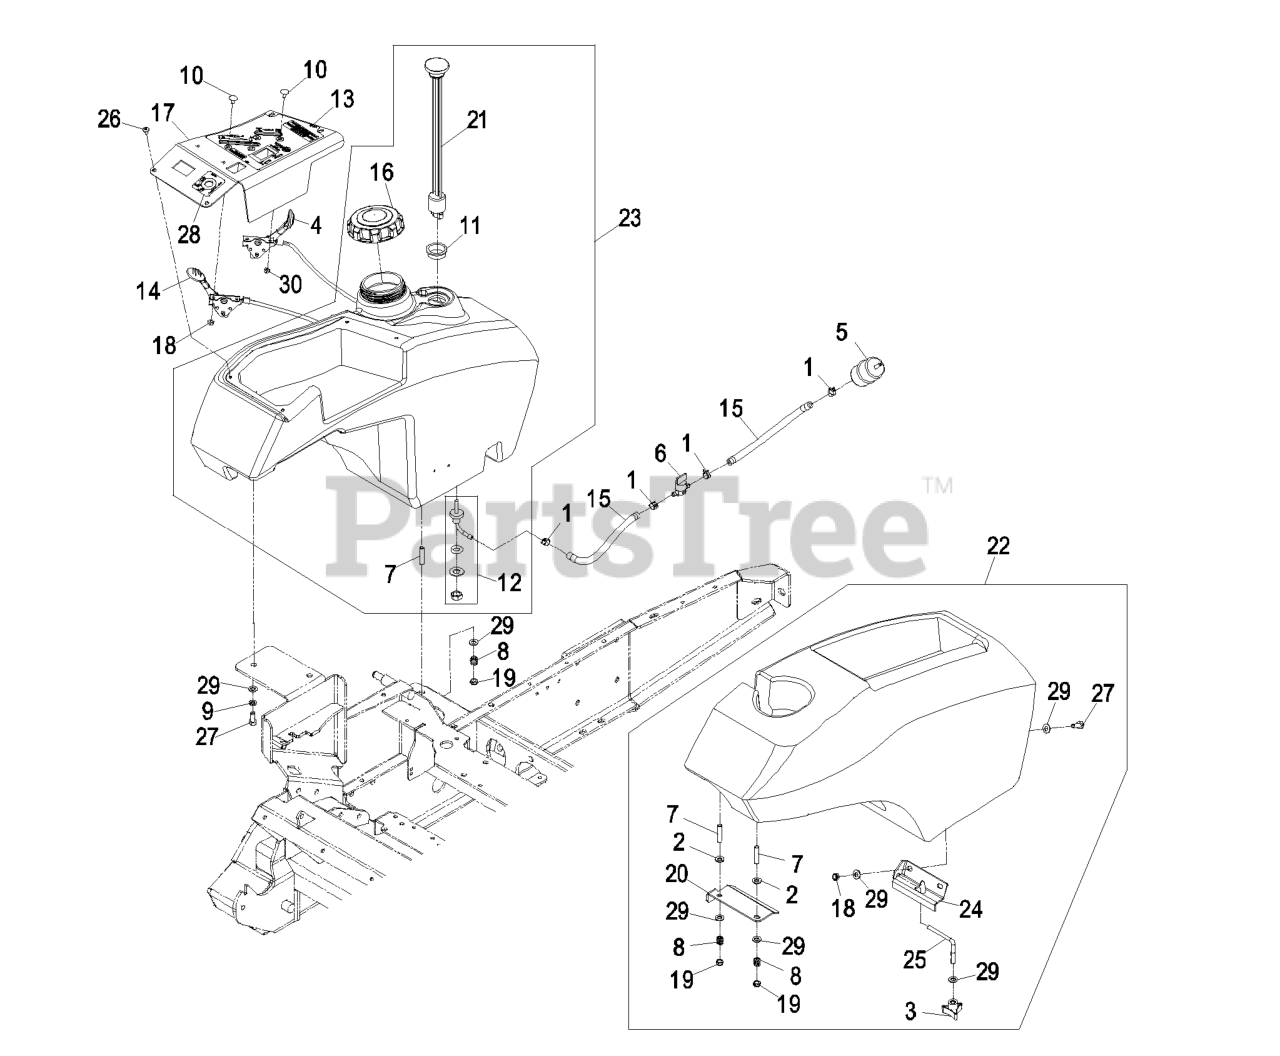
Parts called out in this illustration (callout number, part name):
2	WASHER-SPRING
3	KNOB-3 PRONG
4	CONTROL,CHOKE
5	Kohler Part No. 2405010 Fuel Filter
6	VALVE-FUEL
7	STUD
8	SPRING-TANK, FUEL
9	WASHER-LOCK
10	BOLT-CARR
11	CONTACT ORDER SERVICES
12	FITTING-FUEL, BULKHEAD
13	DECAL,CONTROL FMZ A/C
14	CONTROL,THROTTLE
15	HOSE-FUEL
16	CAP-FUEL, GAS
17	ASM,CONTROL PANEL FMZ A/C
18	NUT-LOCK, NI
19	NUT-LOCK, NI
20	HOOK,FENDER (PLATED)
21	Gauge, Fuel
22	ASM,FENDER FMZ
24	BRACKET,FENDER
25	BOLT,FENDER
26	SCREW-PPH
27	SCREW-HH
28	DECAL,IGNITION
29	WASHER-PLAIN
